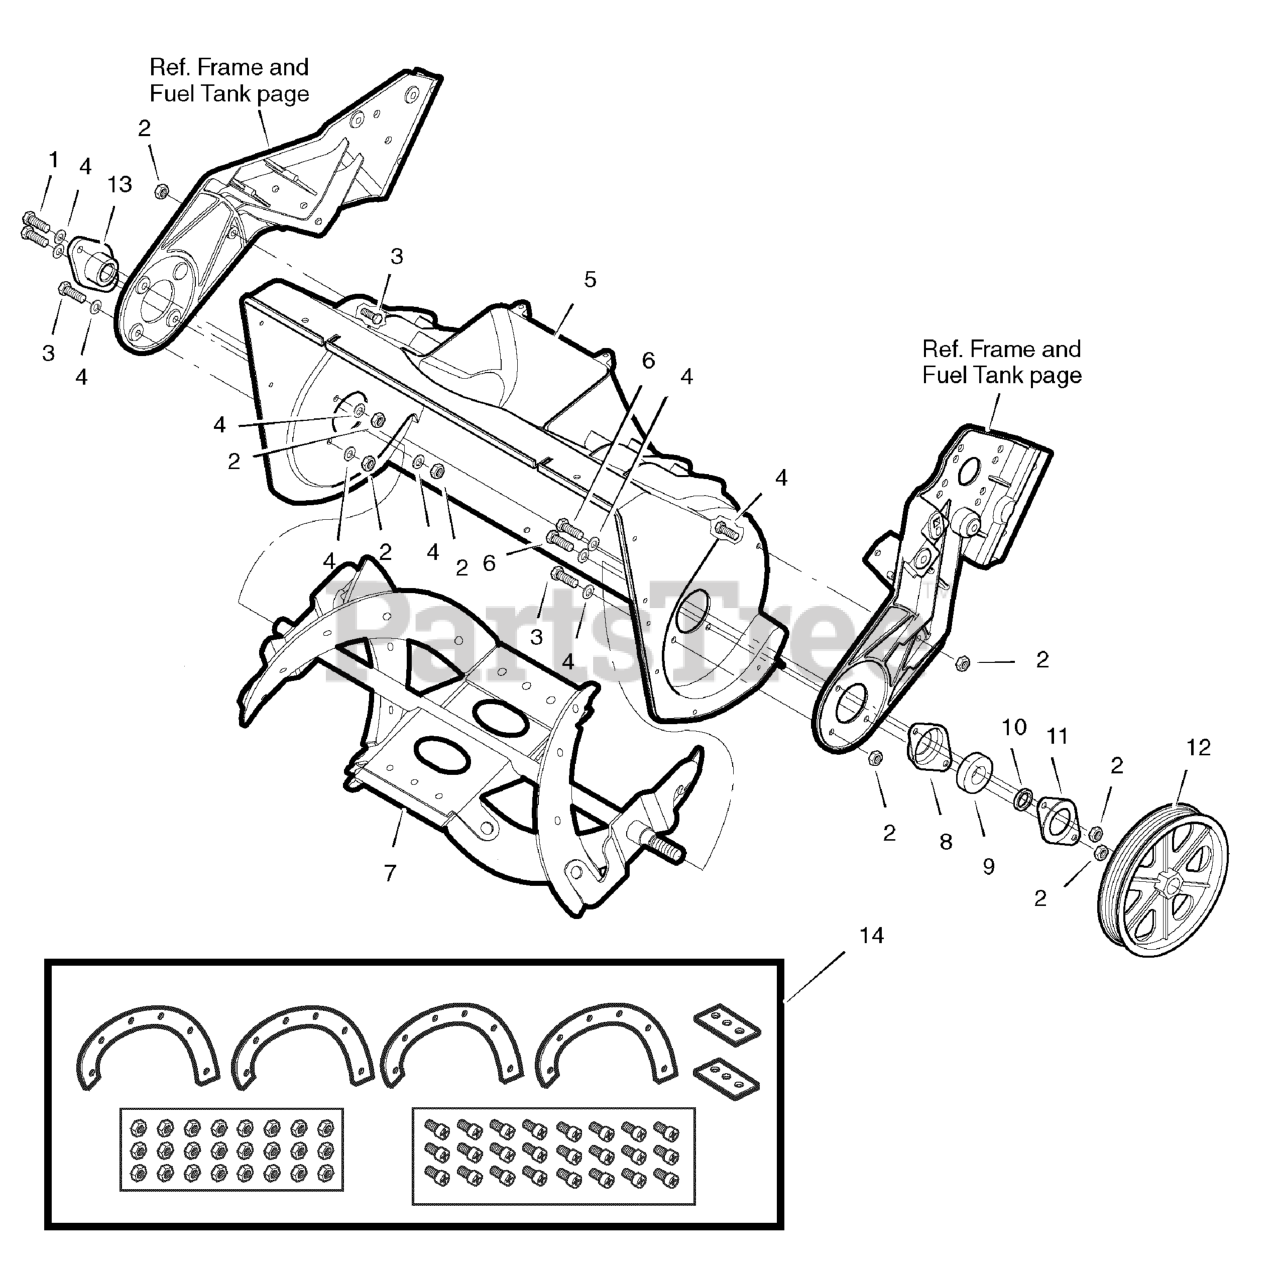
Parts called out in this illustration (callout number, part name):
1	SCREW, 1/4 - 20 x 1
2	NUT, Hex, 1/4 - 20
3	SCREW, 1/4 - 20 x 3/4
4	WASHER, Flat
5	HOUSING ASSEMBLY, Auger
6	SCREW, 1/4 - 20 x 5/8
7	AUGER ASSEMBLY, 22"
8	BEARING, Retainer
9	Bearing
10	SLEEVE, Spacer
11	PLATE, Bearing Retainer
12	PULLEY, Auger Drive V6
13	BEARING, Flange
14	AUGER FLIGHTING REPLACEMENT KIT
